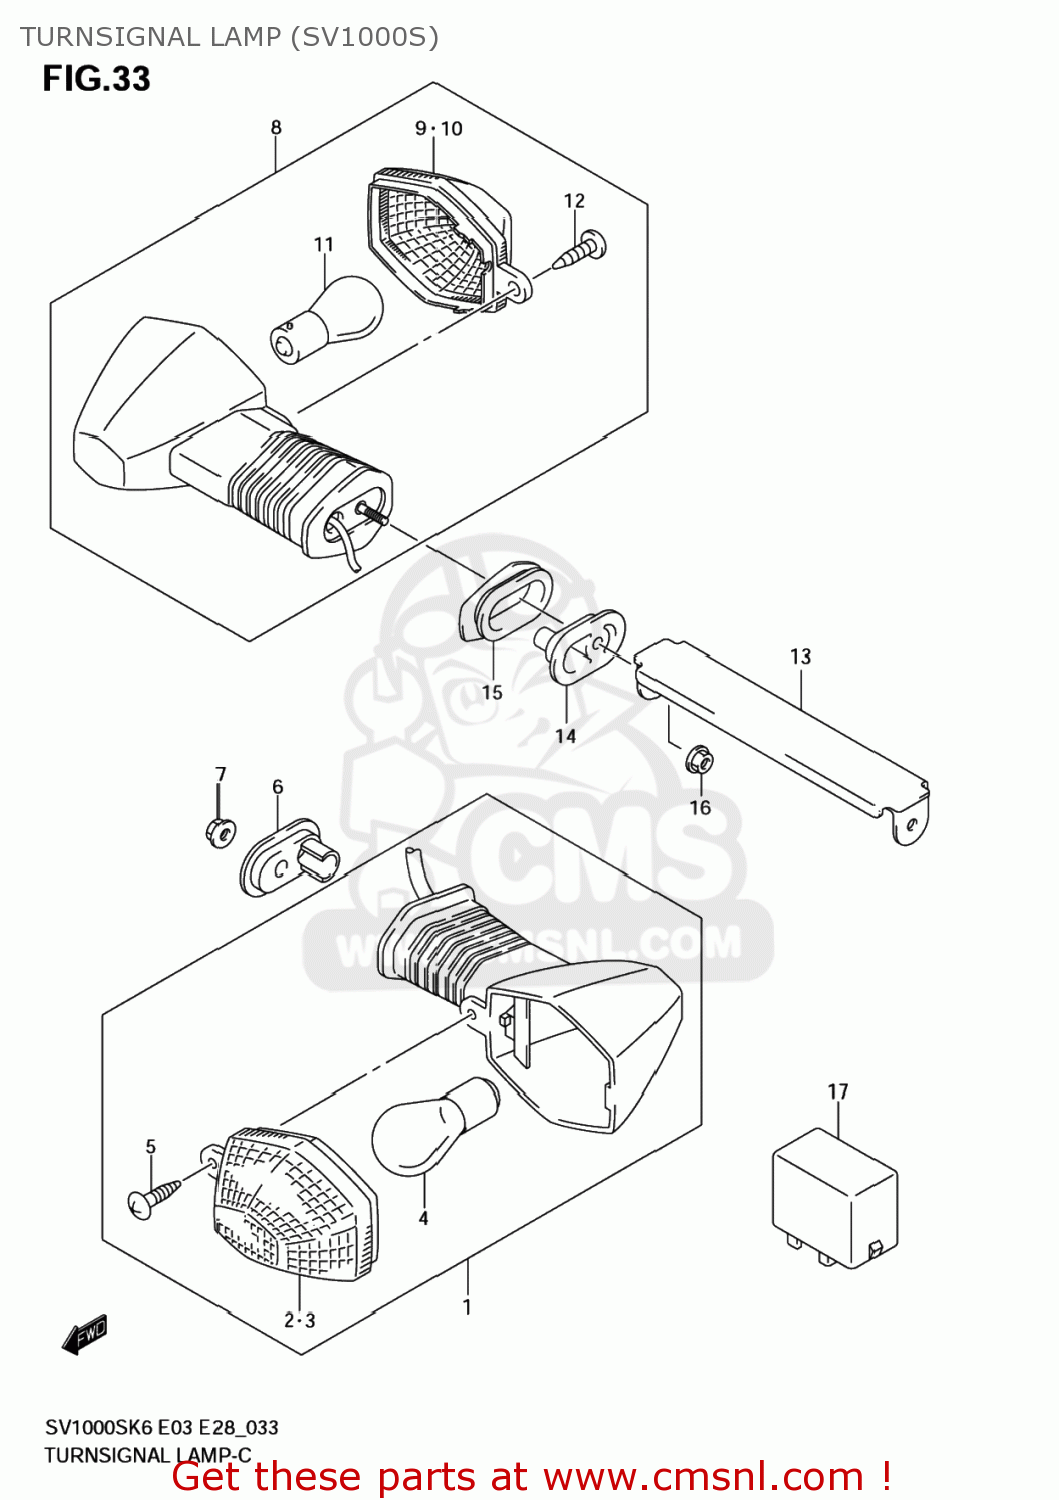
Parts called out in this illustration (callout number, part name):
1	LAMP ASSY,FR TURN,R
2	LENS
3	LENS
4	BULB(12V21W)
5	SCREW
6	PLATE,TURNSIGNAL LAMP
7	NUT
8	LAMP ASSY,RR TURNSIGNAL,R
9	LENS
10	LENS
11	BULB(12V21W)
12	SCREW
13	BRACKET,RR TURNSIGNAL
14	PLATE,RR TURN SIGNAL
15	CUSHION,RR
16	NUT
17	RELAY ASSY,TURNSIGNAL LAMP
